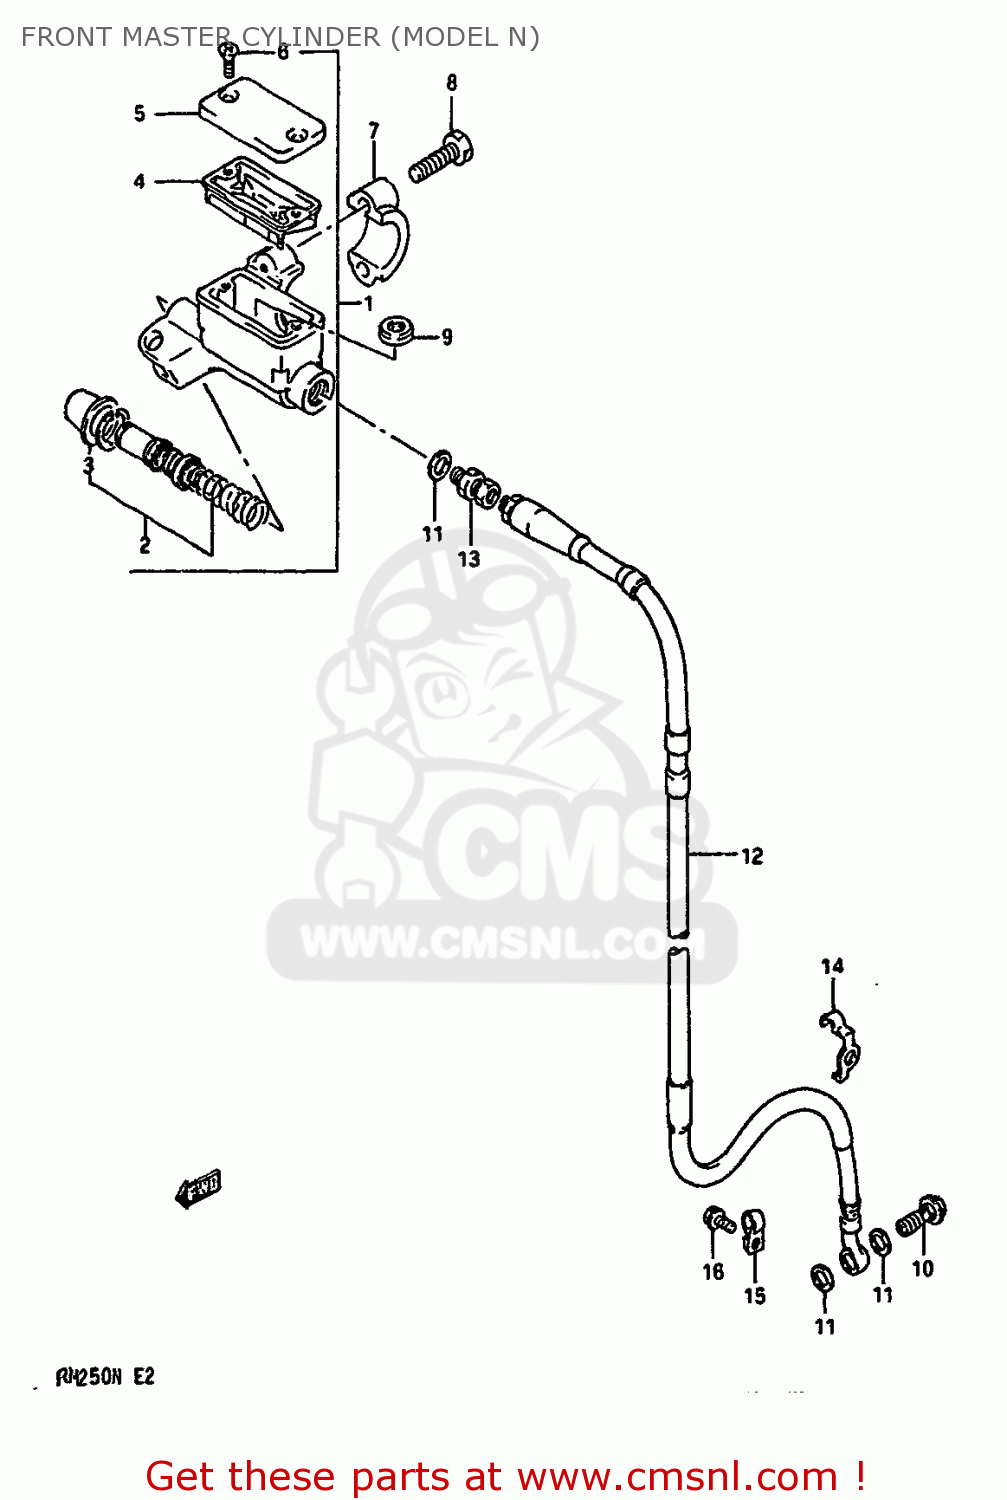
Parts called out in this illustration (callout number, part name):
1	CYLINDER ASSY,FR MASTER
2	PISTON & CUP SET
3	BOOT
4	DIAPHRAGM
5	CAP
6	SCREW
7	HOLDER
8	BOLT
9	SEPARATOR
10	BOLT UNION
11	WASHER(10X15X1.5)
12	HOSE,FRONT BRAKE
13	ADAPTOR,BRAKE HOSE
14	CLAMP,FRONT BRAKE HOSE
15	CLAMP,FR BRAKE HOSE NO.2
16	BOLT
